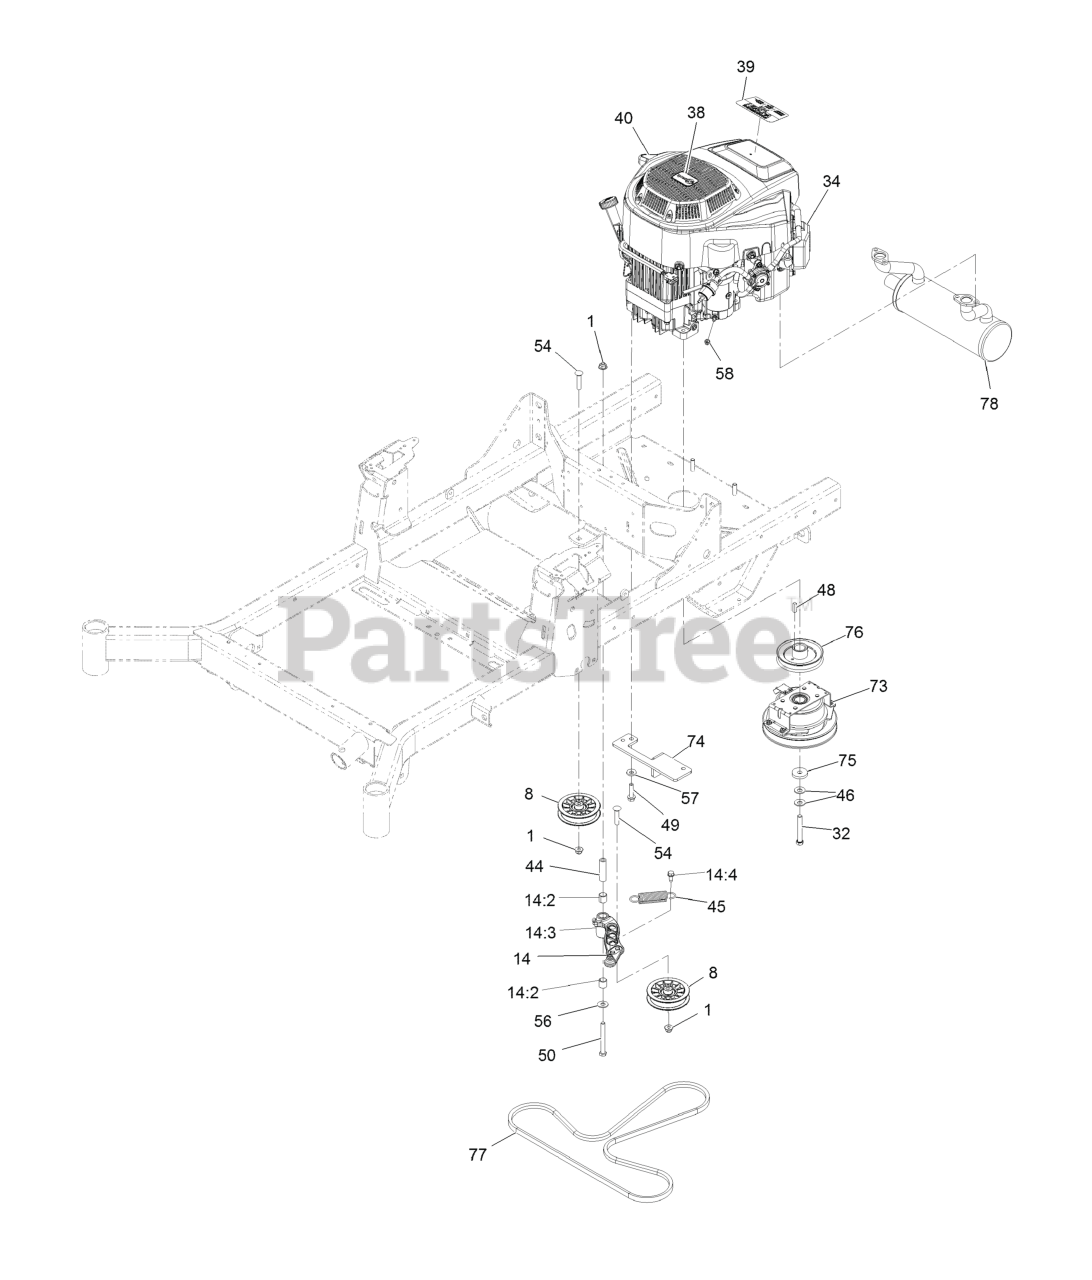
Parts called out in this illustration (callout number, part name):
1	NUT-HF, NI
8	PULLEY-FLAT IDLER
14	IDLER ARM ASM
14:2	SLEEVE-BEARING
14:3	FITTING-GREASE, 90 DEG
14:4	SCREW-THD ROLL, HWH
32	SCREW-HH W/LOCTITE
34	ENGINE-2P77F
39	DECAL-ENGINE 708 V-TWIN EXMARK
40	DECAL-DRAIN, OIL
44	BUSHING-PIVOT, IDLER
45	SPRING-EXTENSION
46	WASHER-SPRING
49	SCREW-HWH
50	SCREW-HH
54	SCREW-CARR
56	WASHER-FLAT
57	WASHER-BELLEVILLE
73	Clutch 1.00
74	ANCHOR CLUTCH
75	WASHER-CLUTCH
76	Sheave-Engine
77	V-BELT
78	MUFFLER
